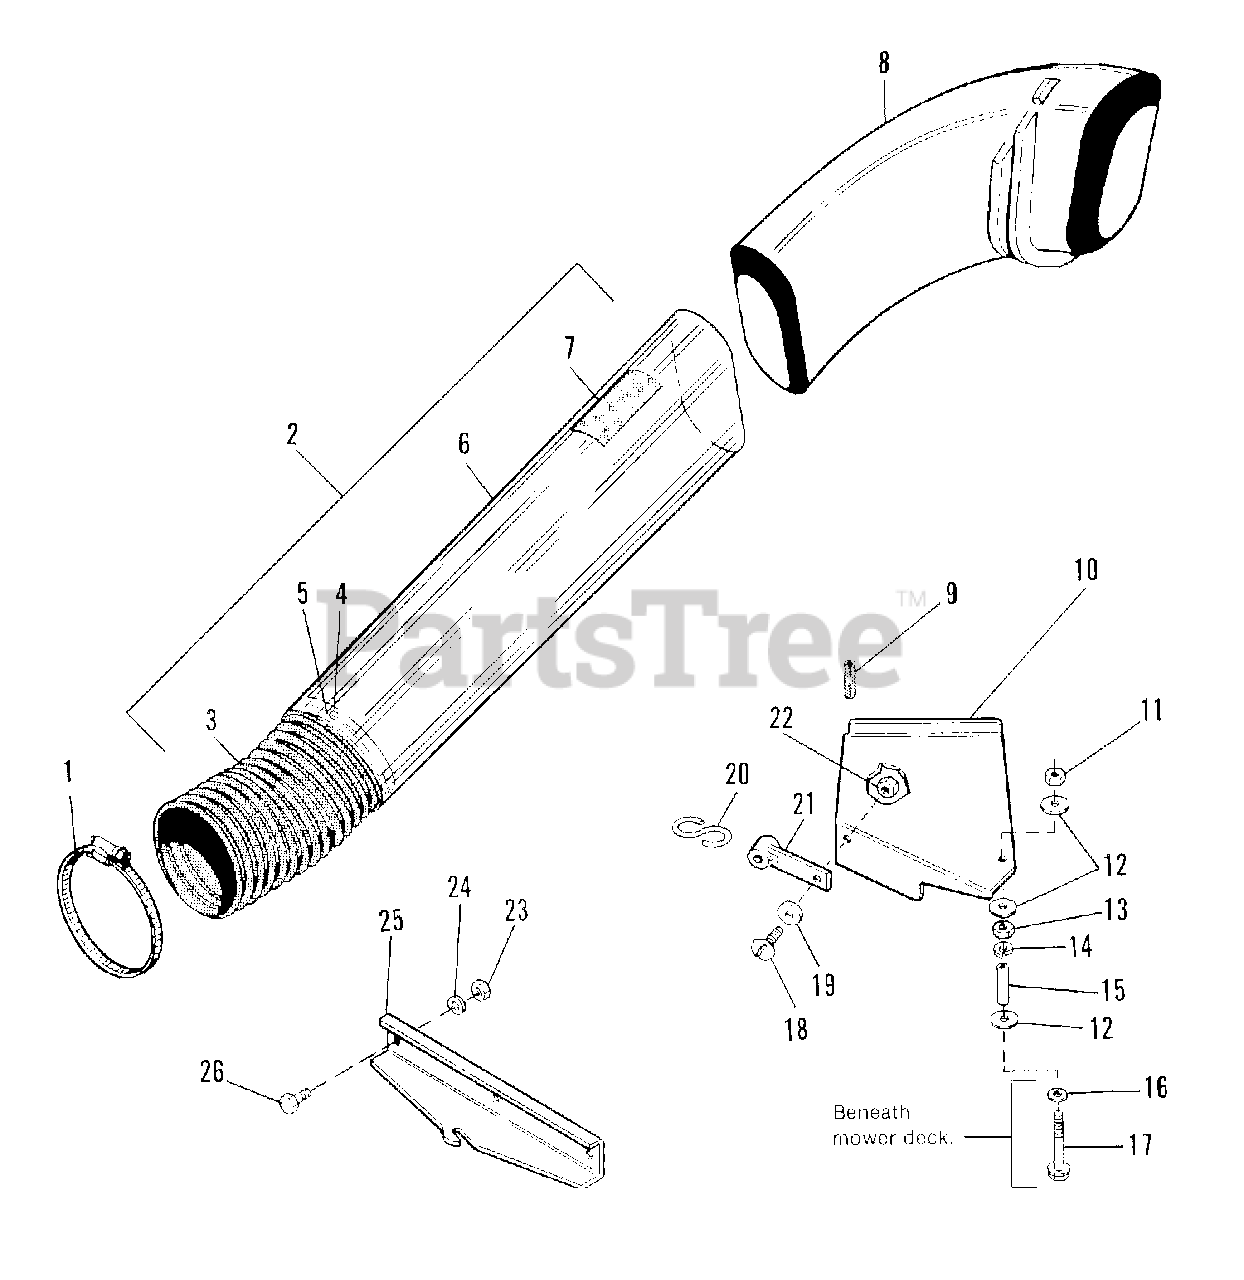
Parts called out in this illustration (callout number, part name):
2	TUBE ASSEMBLY. (Incl. Ref. Nos. 3 - 7)
3	HOSE, Exhaust
5	WASHER, Rivet
7	DECAL, Cleaning lnstructions
10	COVER ASSEMBLY
11	NUT, Hex, 5/16-18
12	WASHER, Special
13	NUT, Hex, Centerlock, 5/16-18
14	LOCKWASHER, 5/16
16	WASHER, 5/16
17	CAPSCREW, Hex Head, 5/16-18 x 5-1/2
18	SCREW, Truss Head, Phillips, #10-32 x 1/2
19	WASHER, Special
21	STRAP, Arbor Cover
22	NUT, Hex, Centerlock, #10-32
23	NUT, Hex, 3/8-16
24	LOCKWASHER, 3/8
25	SUPPORT, Attachment
26	CAPSCREW, Hex Head, 3/8-16 x 1
